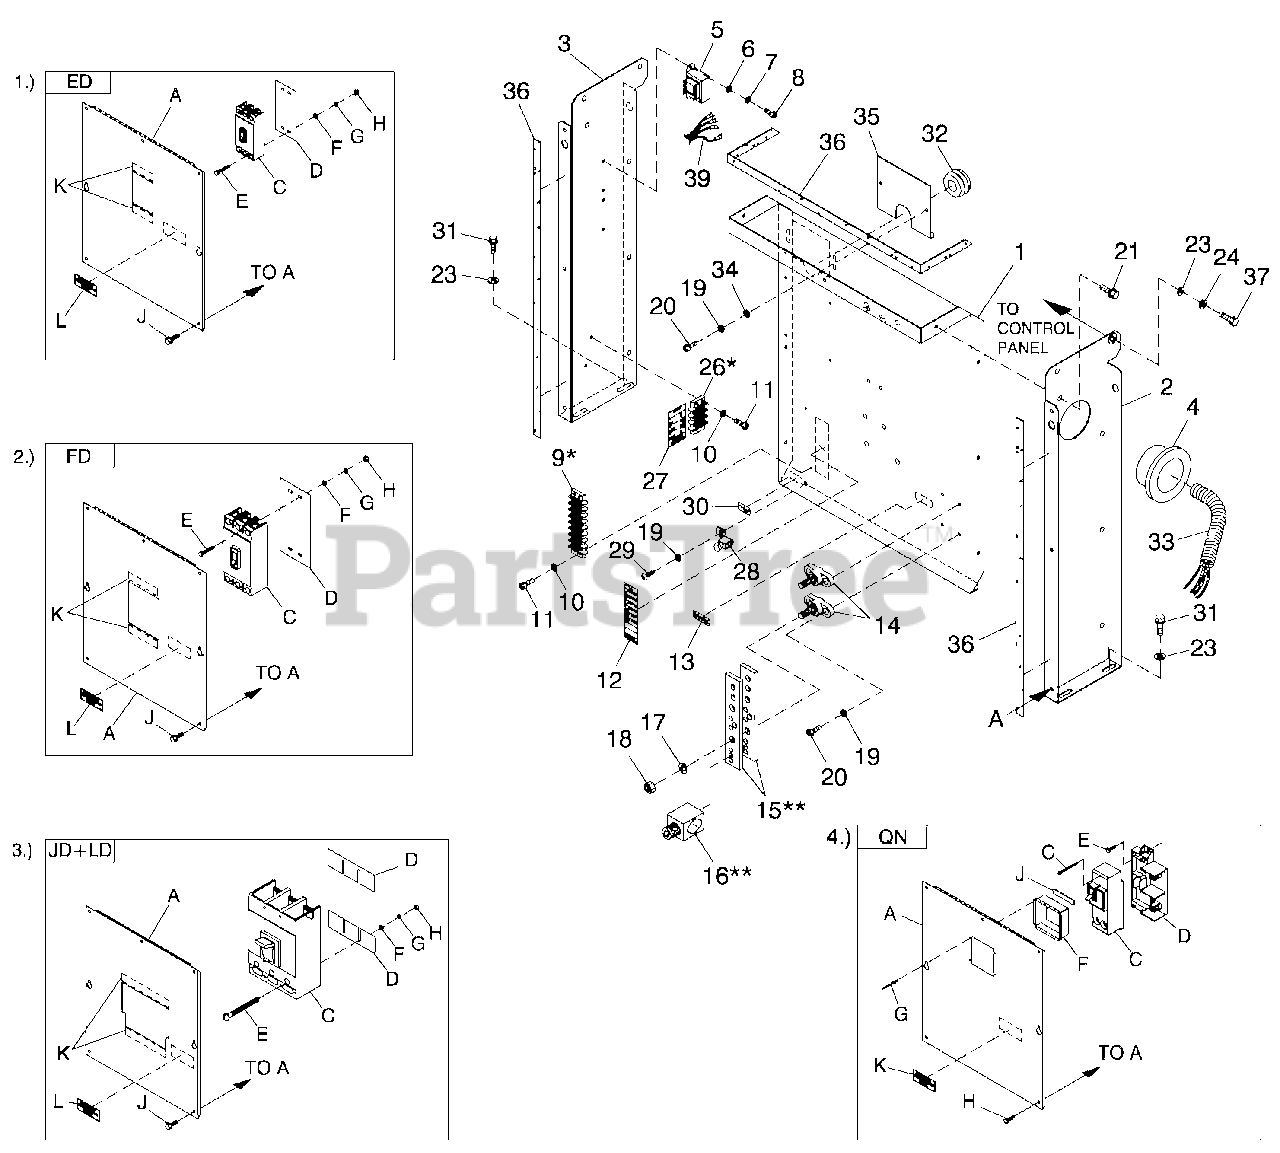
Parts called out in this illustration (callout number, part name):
1	PAN CB CONN BOX
1	UL CIRCUIT BREAKER (ED)
2	STAND RH CONTROL
2	UL CIRCUIT BREAKER (FD)
3	STAND LH CONTROL
3	UL CIRCUIT BREAKER (JD+LD)
4	BUSHING SNAP SB-2.5-31
4	UL CIRCUIT BREAKER (QN)
5	XFMR DUAL 120V/16V (FOR 120/240V & 277/480V UNITS)
6	WASHER FLAT M4
7	WASHER LOCK #8-M4
8	SCREW PHTT M4-0.7 X 10 ZYC
9	BLOCK TERM 20A 8 X 6 X 1100V
10	WASHER LOCK #6
11	SCREW PHTT #6-32 X 1/2 ZYC
12	DECAL UTIL SENSE/CUST CONN
13	DECAL NEUTRAL
14	JUNCTION BLOCK 3/8-16
15	BUS BAR NEUTRAL BLOCK 390
16	LUG SLDLSS 600/250-1/0 X 1/4-28
17	WASHER LOCK 3/8
18	NUT HEX 3/8-16 STEEL
19	WASHER LOCK M5
20	SCREW PHTT M5-0.8 X 16 ZYC
21	SCREW THF M6-1 X 16 N WA Z/JS
23	WASHER FLAT 1/4-M6 ZINC
24	WASHER LOCK M6-1/4
26	BLOCK TERM 20A 6 X 3 X 1100V
27	DECAL CUST CONN 120V UTILITY
28	LUG SLDLSS #6-14 X 13/64 CU
29	SCREW HHTT #10-32 X 3/8 CZ
30	DECAL GROUND LUG
31	SCREW HHTT M6-1.0 X 16 ZYC
32	GROMMET 1.25 X .25 X .75
33	CONDUIT FLEX 2.0" ID (36" LG)
34	WASHER FLAT M5
35	PLATE WIRE SNGL GALV
36	TAPE ELEC 1/2 FOAM (AS REQ'D)
37	SCREW HHC M6-1.0 X 16 G8.8
39	HARNESS, TRANSFORMER ADAPTER
A	COVER ED CB SHORT STND
C	CB 0050A 3P 480V S ED4 LL
D	INSULATOR CB S (ED-3P)
E	SCREW RHM #10-32 X 4-1/2
F	WASHER FLAT #10 ZINC
G	WASHER LOCK #10
H	NUT HEX #10-32 STEEL
J	SCREW THF M6-1 X 16 N WA Z/JS
K	TAPE ELEC 1/2 FOAM (AS REQ'D)
L	DECAL CUSTOMER CONNECT INSIDE
A	COVER CB CONN BOX
C	CB 0150A 3P 600V S FD6 LL
D	INSULATOR CB FD FRAME 30MIL
E	SCREW SHC 1/4-20 X 4.5 G8.8 NZ
F	WASHER FLAT 1/4-M6 ZINC
G	WASHER LOCK M6-1/4
H	NUT HEX 1/4-20 STEEL
A	COVER JD/LD CB SHRT STAND
C	CB 0300A 3P 600V S JD6 LL
D	INSULATOR CIRCUIT BR. JD/LD
E	SCREW RHM 1/4-20 X 3
A	COVER QN FRM CB
C	CB 0150A 2P 240V S QN2 LL
D	BASE, QN CIRCUIT BREAKER
E	SCREW HHTT M5-0.8 X 10 BP
F	COVER QN CB DISH
G	RIVET POP .125 X .275 SS
H	SCREW THF M6-1X16 N WA Z/JS
J	TAPE ELEC 1/2 FOAM (AS REQ'D)
K	DECAL CUSTOMER CONNECT INSIDE
